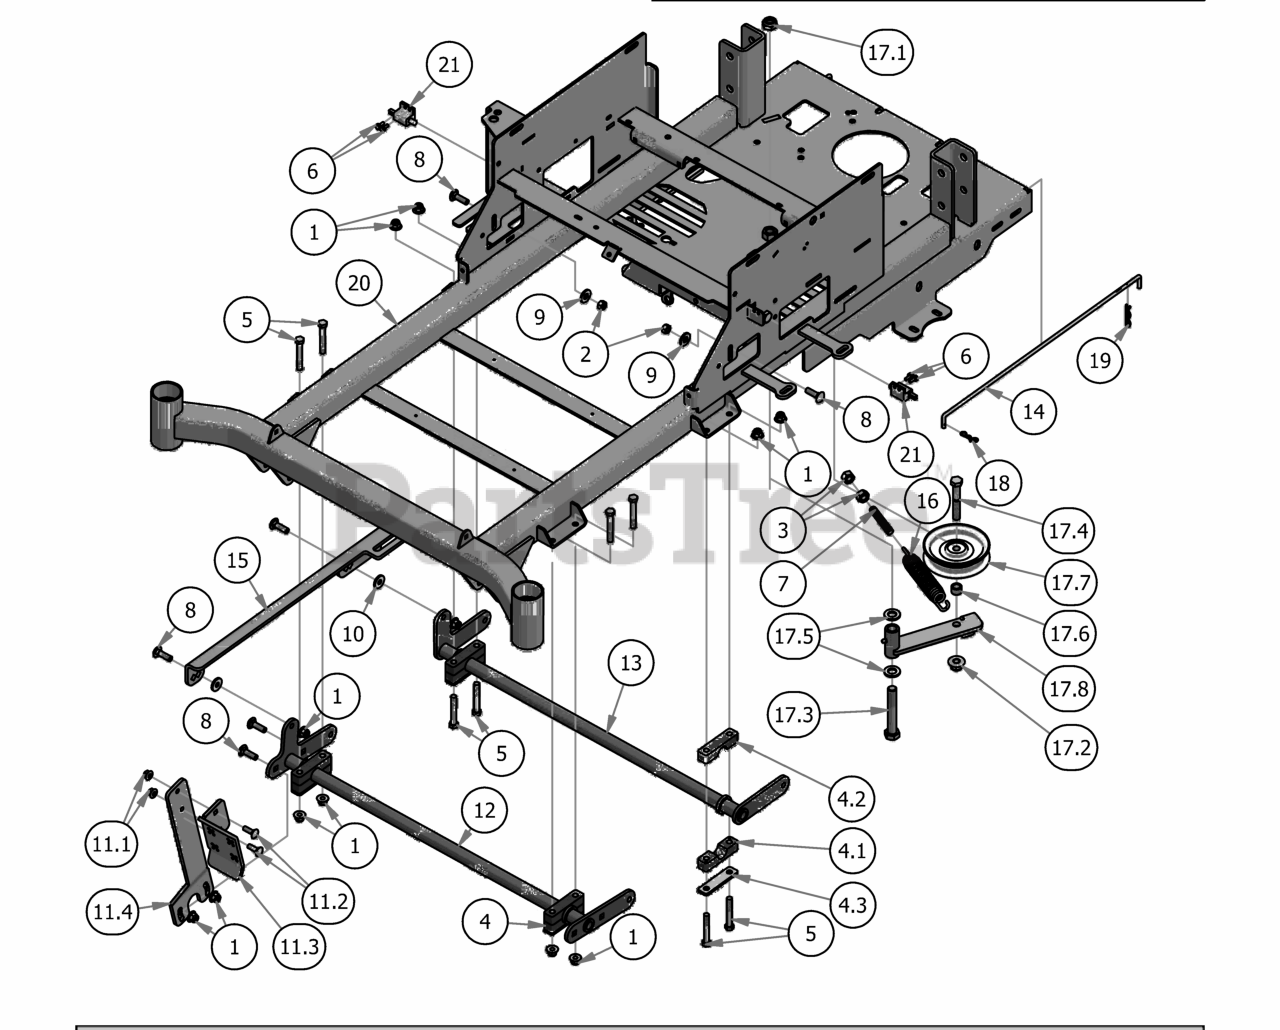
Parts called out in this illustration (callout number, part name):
1	3/8 Nylock Flange Nut
2	3/8" Hex Nut
3	1/2" Hex Nut
4	Pillow Block Kit
4.1	Pillow Block MZ male
4.2	Pillow Block MZ female
4.3	Pillow Block Strap
5	3/8-16 x 2 1/2" Hex Bolt
6	12-24x 1/2 HWH Bolt
7	All Thread-Pump Idler Tensioner
8	3/8" x 1 1/4" Carriage Bolt
9	3/8" Flat Washer
10	.360 ID Plastic Washer
11	Foot Pedal Assembly
11.1	5/16" Nylon Flange Nut
11.2	5/16" x 1" Carriage Bolt
11.3	2017 MZ/ZT Shallow Foot Pedal
11.4	2017 MZ/ZT Deck Pedal Lever
12	Actuator Bar Front- 2017 MZ/ZT
13	Actuator Bar Rear- 2017 MZ/ZT
14	ZT Neutral level rod 2011
15	2017 MZ/ZT Actuator Linkage
16	Deck Idler Spring
17	ZT Pump Idler
17.1	5/8" Nylock (1/2 Jam)
17.2	1/2-13 Nylon Flange Nut
17.3	5/8" x 4" Hex Bolt
17.4	1/2 x 2-3/4 Hex Bolt
17.5	.630 ID Plastic Washer
17.6	1/2 x 1/2 Spacer
17.7	4 3/4" Idler Pulley
17.8	Pump Idler Bracket
19	Neutral Rod Clip
20	2018 Compact Outlaw Frame
21	Safety Switch
